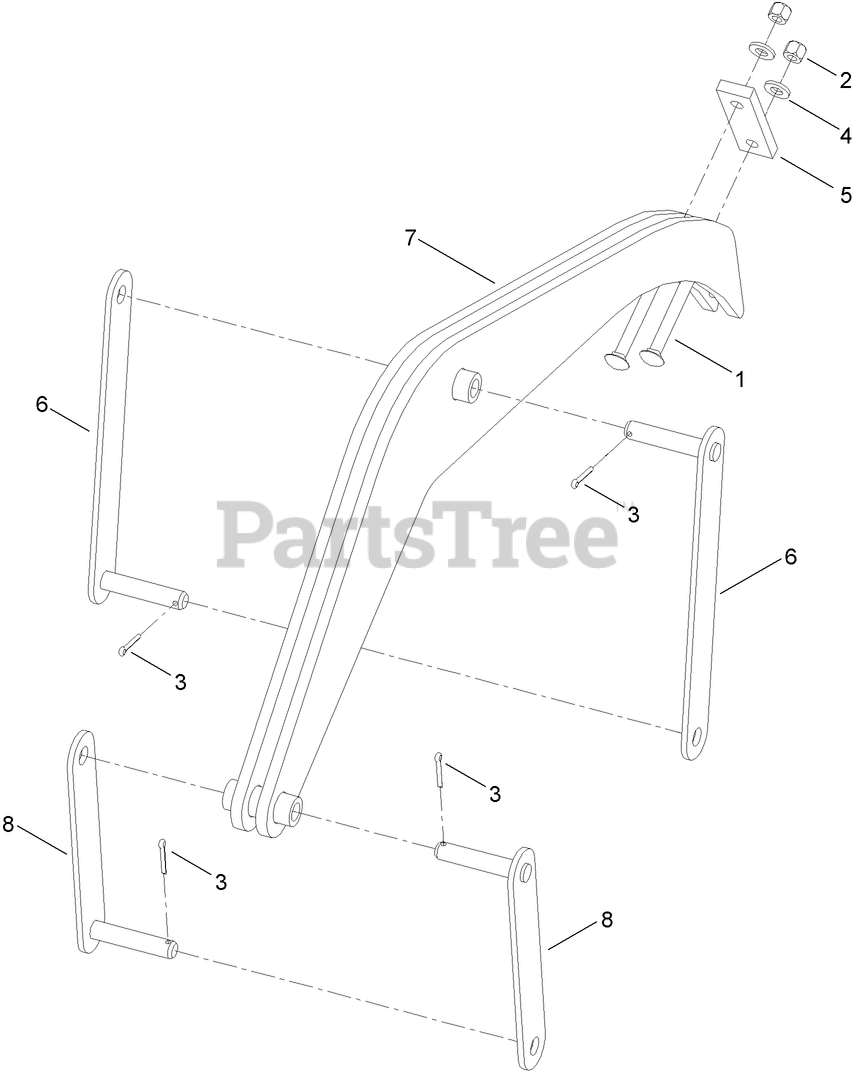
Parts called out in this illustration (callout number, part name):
1	SCREW-CARR
2	NUT-HEX
3	PIN-COTTER
6	LINK-CRUMBER
7	ARM-CRUMBER
8	LINK-SHORT
